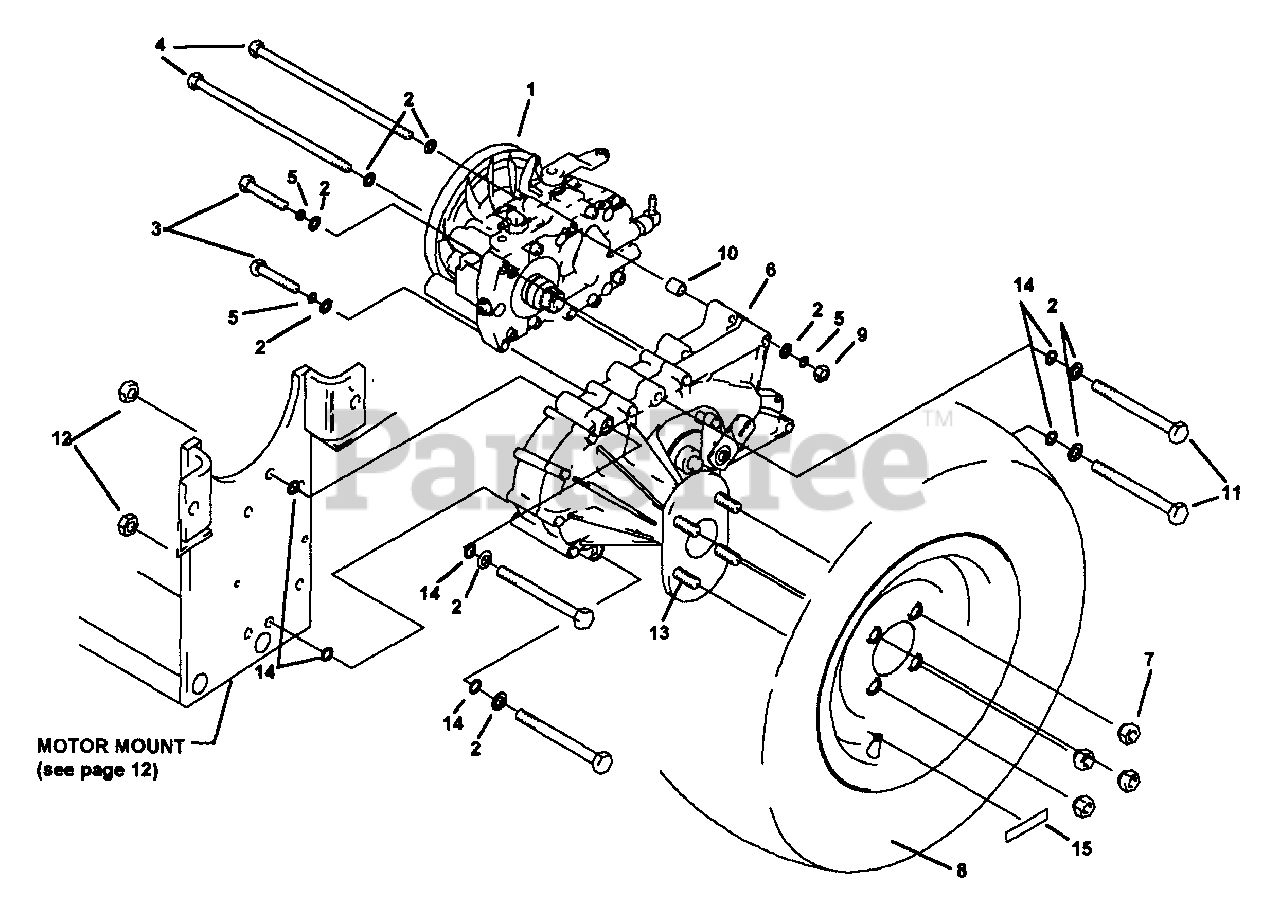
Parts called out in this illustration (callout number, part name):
1	HYDROSTAT TRANSMISSION ASSEMBLY L.H.
1	HYDROSTAT TRANSMISSION ASSEMBLY R.H.
2	WASHER, FLAT STD. 5/16"
3	BOLT, 5/16-18 X 1-3/4" GR.5
5	LOCKWASHER, 5/16" SPLIT SPRING
6	TRANSAXLE, LH, 225-2500L
8	TIRE, 20-10.00-10, 4 PLY W/RIM, DICO BRAND
9	NUT, 5/16-18 PLAIN
10	BUSHING/SPACER
11	BOLT, 3/8-16 X 4" GR.5
12	NUT, 3/8-16 NYLOC
13	LUG BOLT, 1/2-20 X 1-3/4
15	DECAL, TIRE PRESSURE
